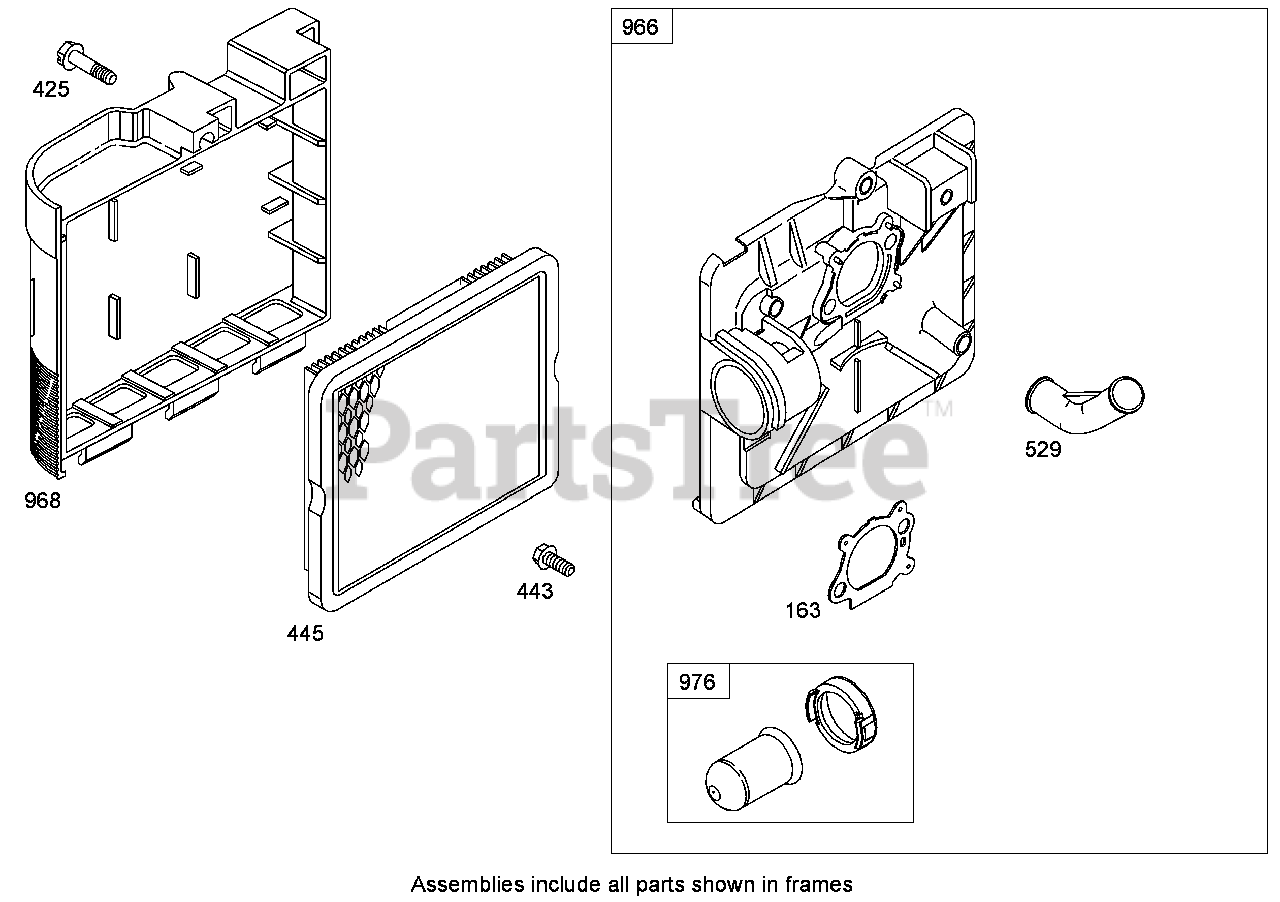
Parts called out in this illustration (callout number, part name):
163	Gasket-Cleaner, Air
425	Screw (Air Cleaner Cover)
443	Screw (Air Cleaner Primer Base)
445	Filter-Cartridge, Air Cleaner
529	Grommet
966	Base-Primer, Air Cleaner
968	Cover-Cleaner, Air
976	Primer-Carburetor
